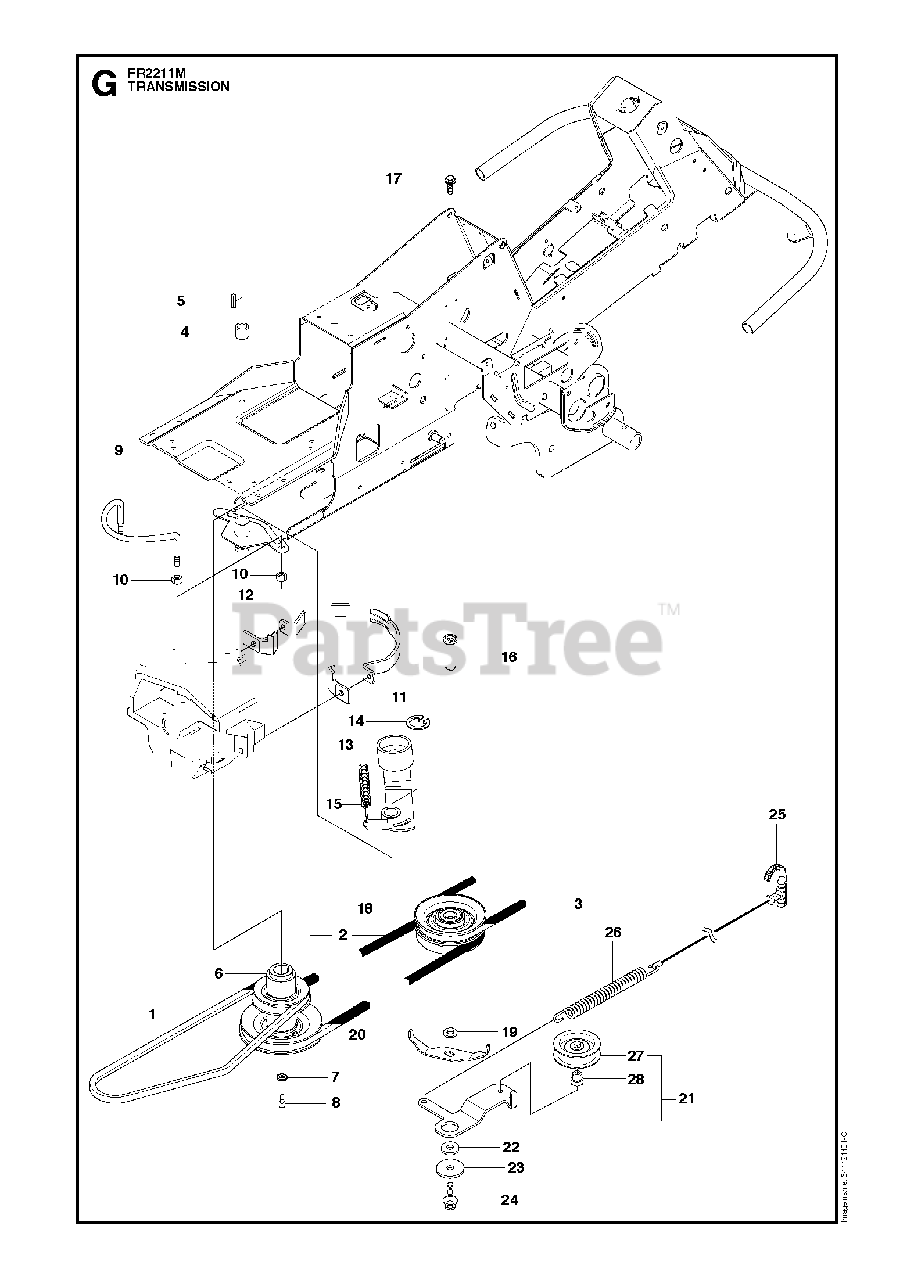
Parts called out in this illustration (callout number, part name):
1	TRANSMISSION BELT
2	BELT
6	PULLEY CPL
9	BELT GUIDE
11	BELT GUIDE CPL., RIGHT
12	BELT GUIDE CPL.,LEFT
13	TENSIONER
14	RETAINING RING SGA 25
16	SHAFT
20	BELT GUIDE
24	BOLT
27	PULLEY
28	BUSHING
